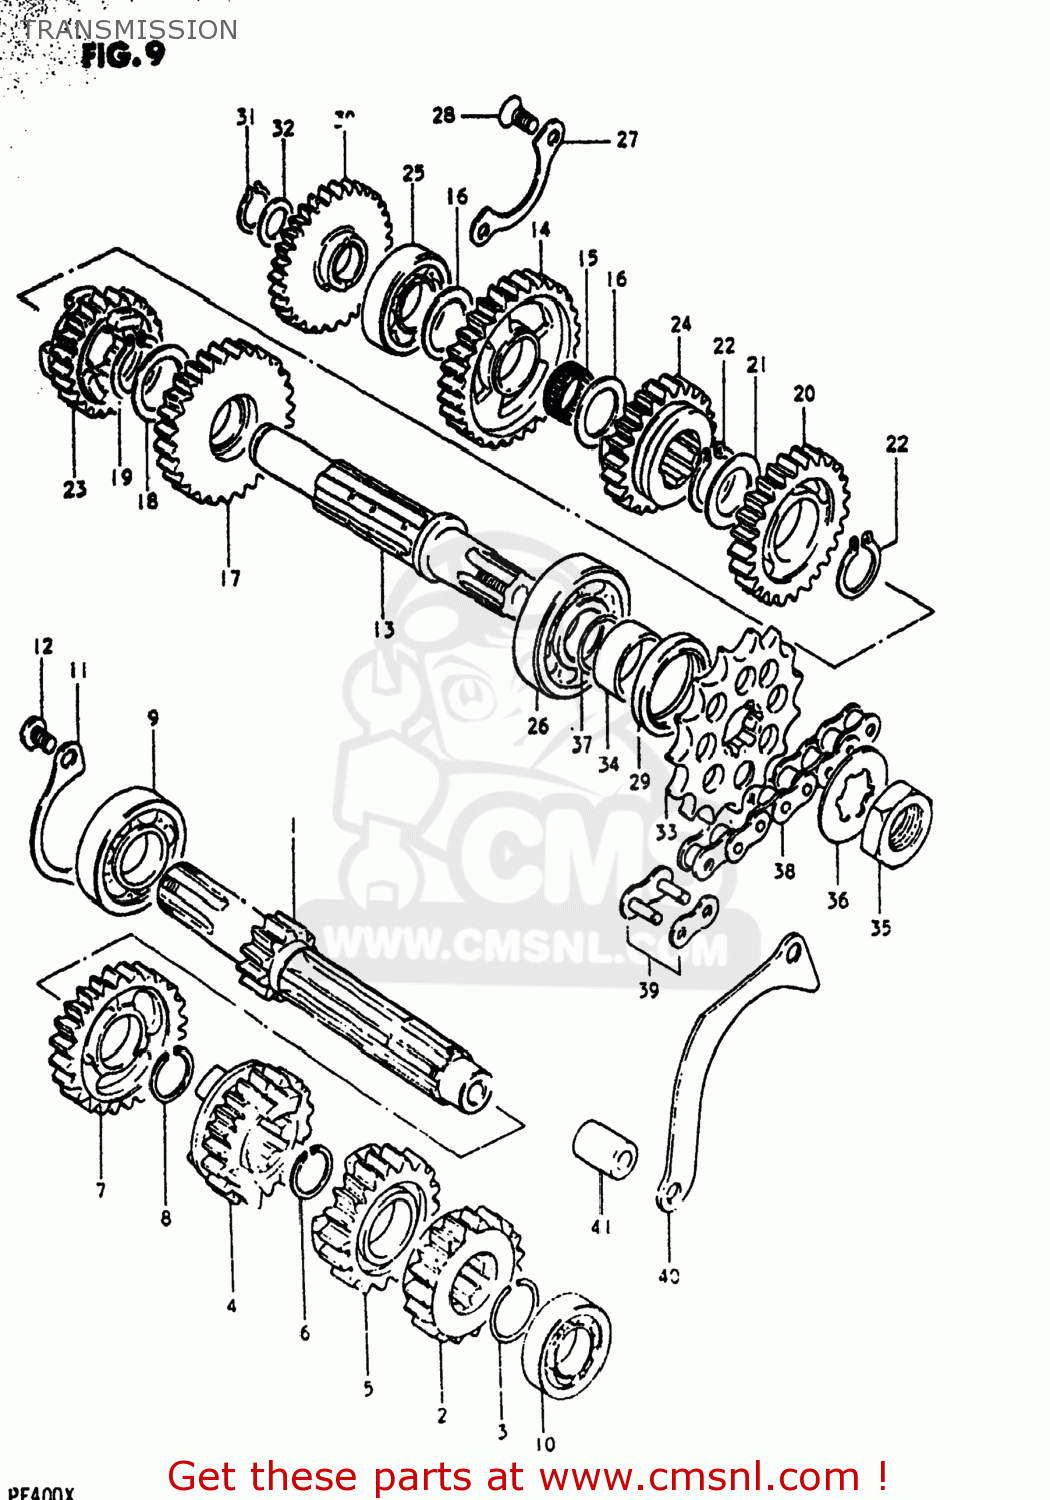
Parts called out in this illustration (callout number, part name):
1	SHAFT,COUNTER
2	GEAR,SECOND DRIVE
3	CIRCLIP
4	GEAR,THIRD DRIVE
5	GEAR,FOURTH DRIVE
6	CIRCLIP
7	GEAR,FIFTH DRIVE
8	CIRCLIP
9	BEARING
10	BEARING
11	PLATE,COUNTERSHAFT BEARING
12	SCREW 6X12
13	SHAFT,DRIVE
14	GEAR,FIRST DRIVEN
15	BEARING(17X21X9.8)
16	WASHER
17	GEAR,SECOND DRIVEN
18	SHIM
19	CIRCLIP
20	GEAR,THIRD DRIVEN
21	WASHER
22	CIRCLIP
23	GEAR,FOURTH DRIVEN
24	GEAR,FIFTH DRIVEN
25	BEARING
26	BEARING
27	PLATE,DRIVESHAFT BEARING
28	SCREW
29	SEAL,OIL(32X42X6)
30	GEAR,KICK STARTER IDLE
31	CIRCLIP
32	WASHER
33	SPROCKET,ENGINE
34	SPACER(22X32X11.5)
35	NUT
36	WASHER,LOCK
37	O RING(D:1.7,ID:22)
38	CHAIN ASSEMBLY,DRIVE
39	JOINT ASSEMBLY,CHAIN
40	PLATE,FR CHAIN GUIDE
41	SPACER(8.6X16X24)
